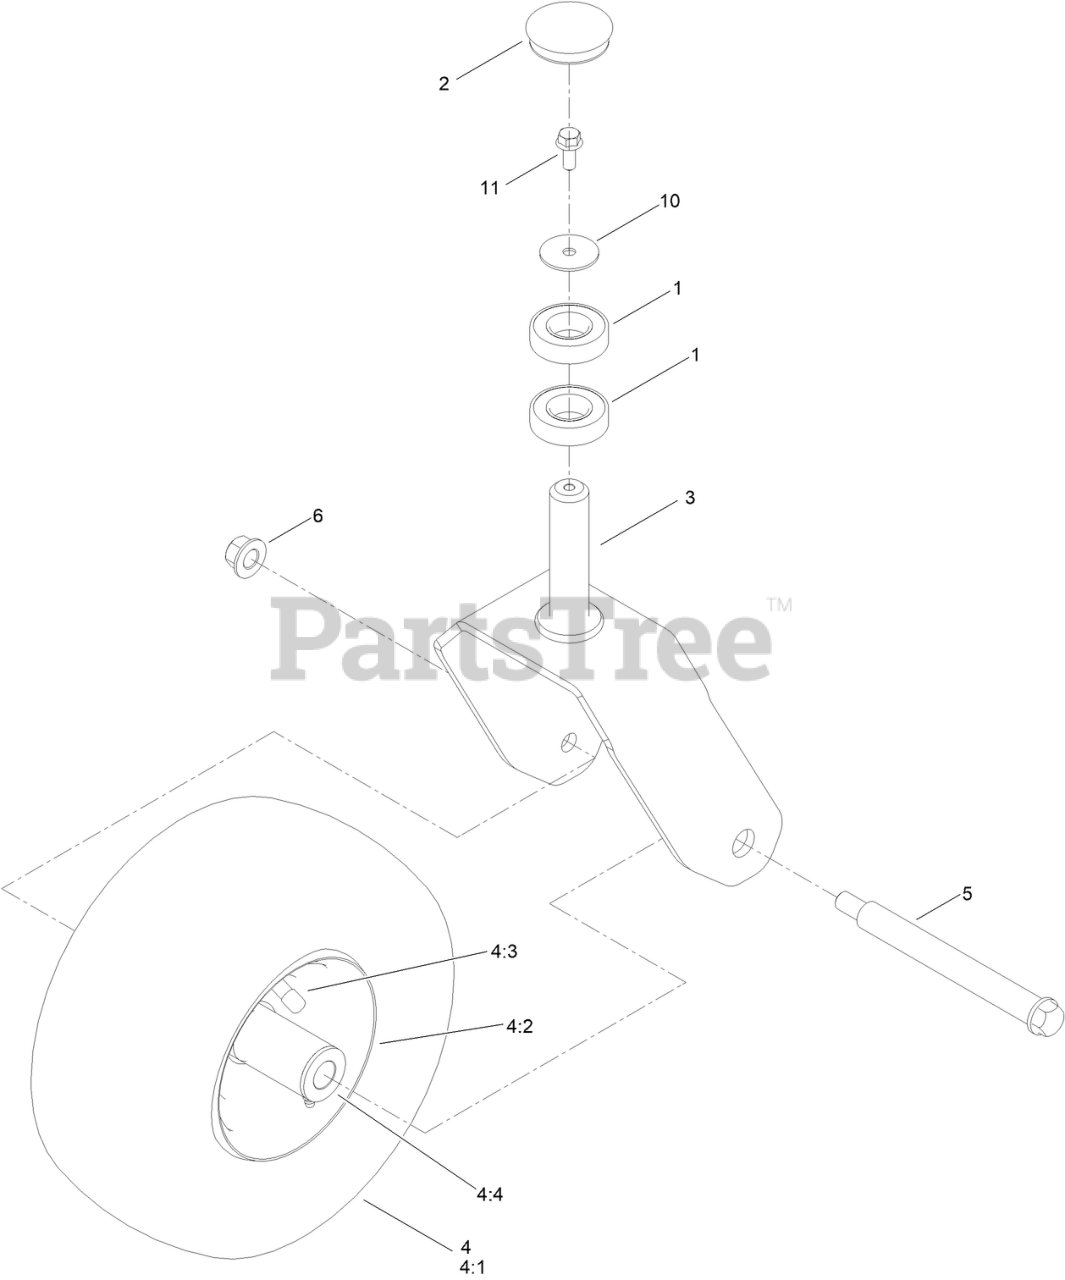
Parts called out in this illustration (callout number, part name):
1	BEARING-BALL
2	CAP,GREASE
3	FORK ASM [RED]
4	WHEEL ASM - CASTER 12X6-5
4:1	TIRE 12X6-5
4:2	WHEEL (W/ ZERK AND BUSHINGS)
4:4	BUSHING-FLANGE
5	SCREW-SHOULDER HHF
6	NUT-LOCK
10	WASHER-FLAT
11	SCREW-HHF
